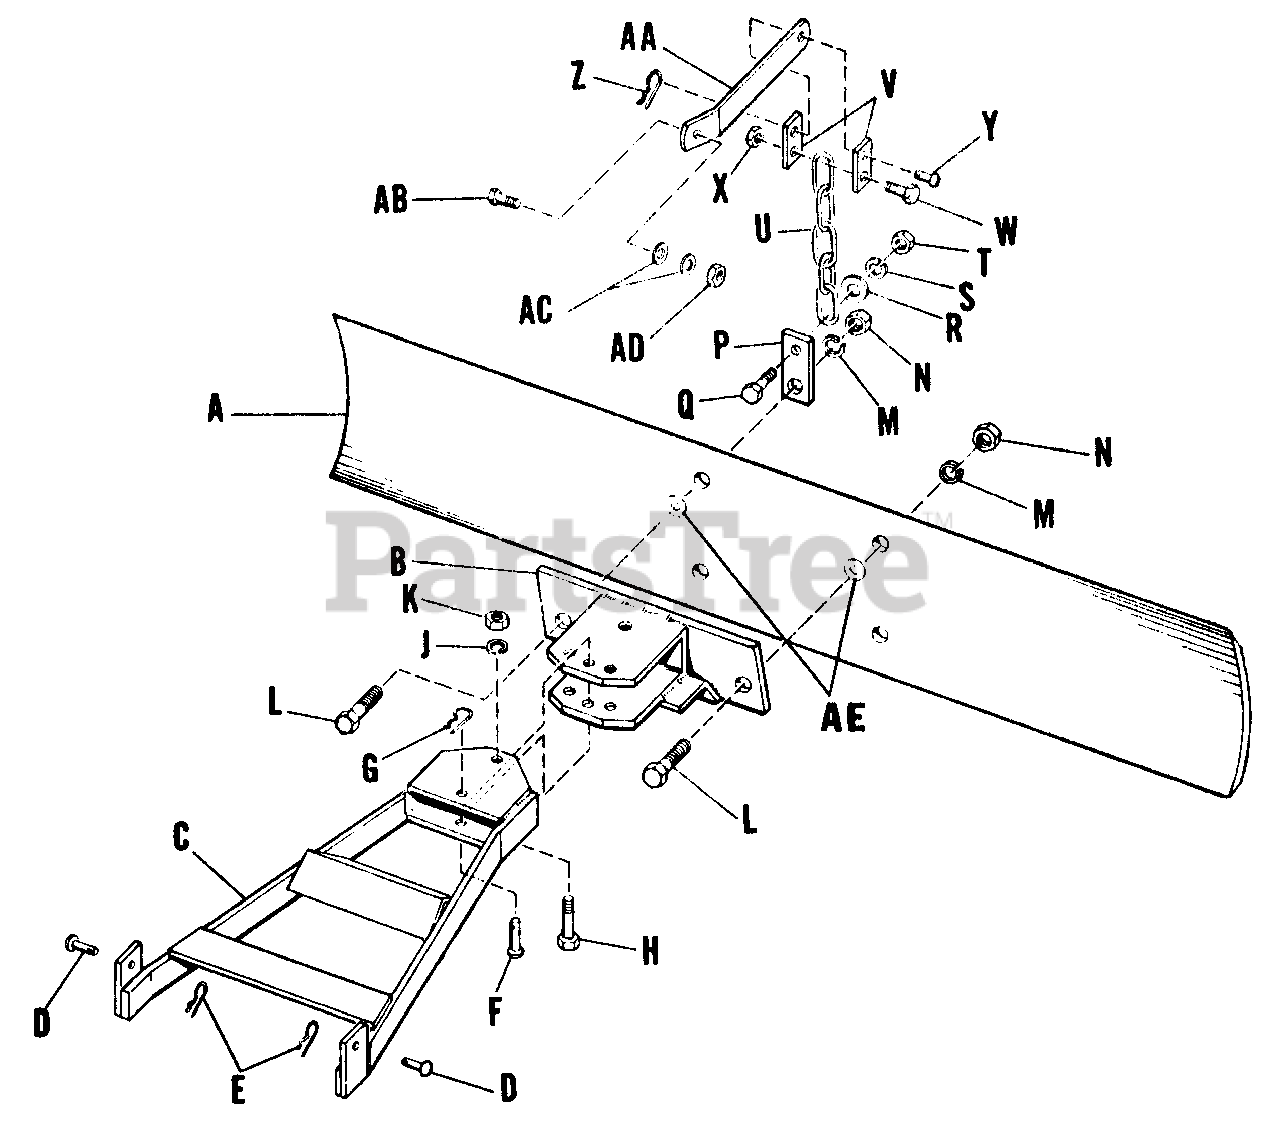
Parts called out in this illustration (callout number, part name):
A	Blade, Grader, 42"
B	Hitch Assembly
C	Draw Bar Assembly
D	Pin
E	Spring Clip
G	Spring Clip
H	Capscrew, Hex Head, 5/8"-11 NC x 3" lg.
J	Lockwasher, 5/8"
K	Nut, Hex, Full, 5/8"-11 NC
L	Capscrew, Hex Head, 5/8"-11 NC x 2" lg.
M	Lockwasher, 5/8"
N	Nut, Hex, Full, 5/8"-11 NC
Q	Capscrew, Hex Head, 3/8"-16 NC x 1 1/4" lg.
R	Plain Washer, 3/8"
S	Lock Washer, 3/8"
T	Nut, Hex, Full, 3/8"-16 NC
U	Chain
W	Capscrew, Hex Head, 3/8"-16 NCx 1 1/4" lg.
X	Nut, Hex, Full, lock, 3/8"-16 NC
Z	Spring Clip
AB	Capscrew, Hex Head, 3/8"-16 NC x 1 1/4" lg.
AC	Plain Washer, 3/8"
AD	Nut, Hex, Full, Lock, 3/8"-16 NC
AE	Flat Washer, 1-1/16"
